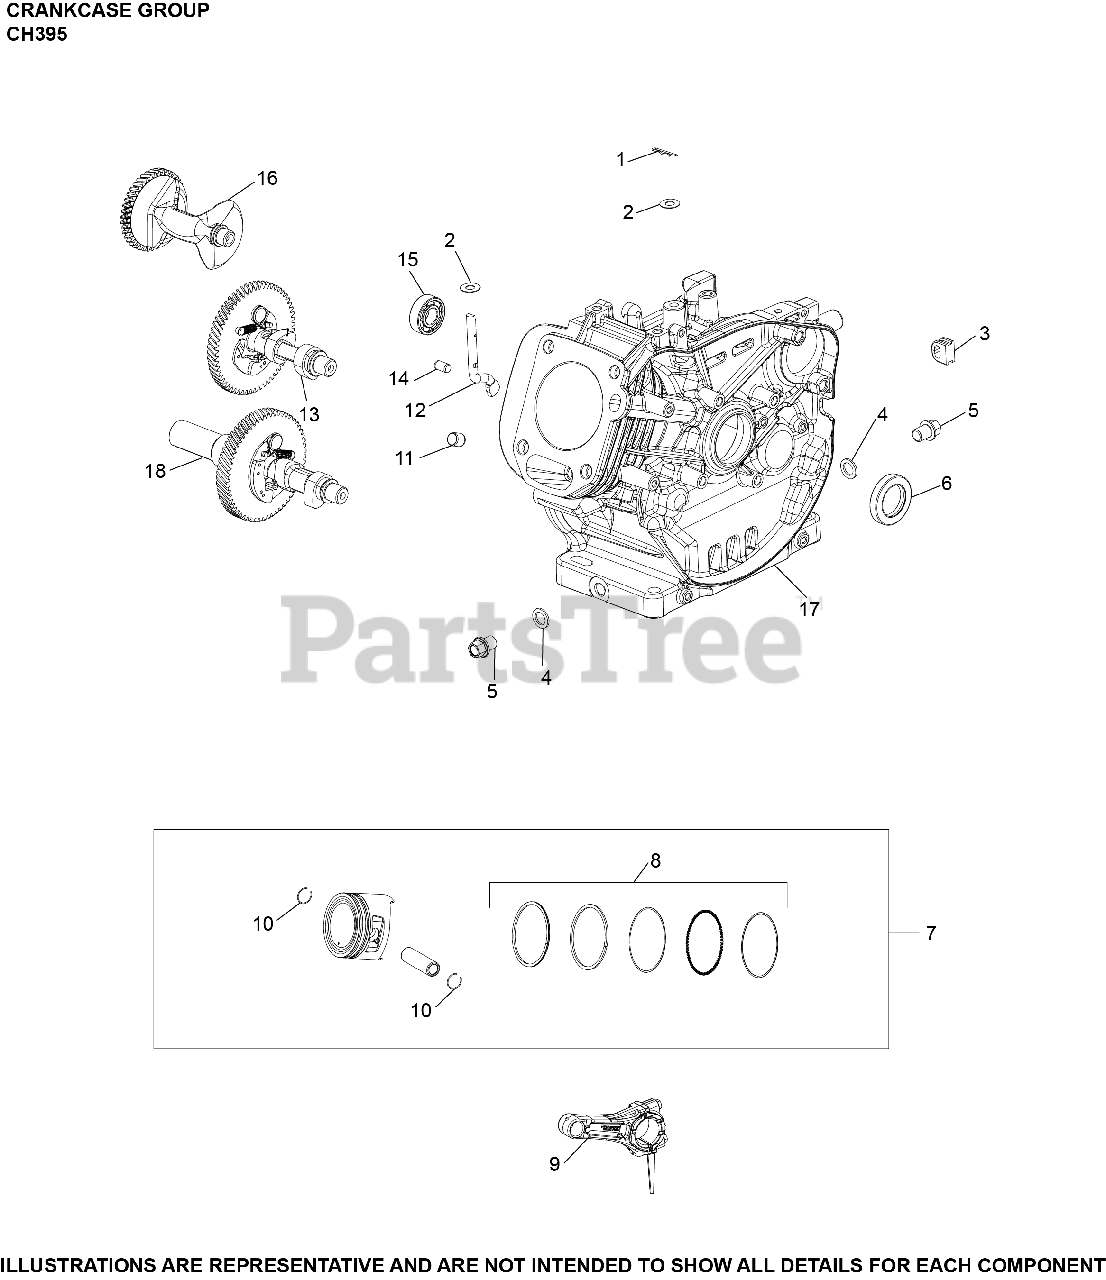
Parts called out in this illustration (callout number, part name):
1	CLIP, GOVERNOR SHAFT
2	WASHER, FLAT
3	GROMMET, CRANKCASE
4	WASHER, DRAIN PLUG
5	KIT, DRAIN PLUG
6	SEAL, RADIAL SHAFT
7	KIT , PISTON & RINGS
8	RING SET (STD), TOP RING 1.48 mm (.058")
8	RING SET (STD), TOP RING 2 mm (.079") USE 17 874 06-S
9	ROD, CONNECTING ASSEMBLY
10	RETAINER, PISTON PIN
11	PIN, DOWEL CYLINDER HEAD
12	SHAFT, GOVERNOR CROSS
13	CAMSHAFT ASSEMBLY
14	PIN, DOWEL
16	SHAFT, BALANCE
17	CRANKCASE
